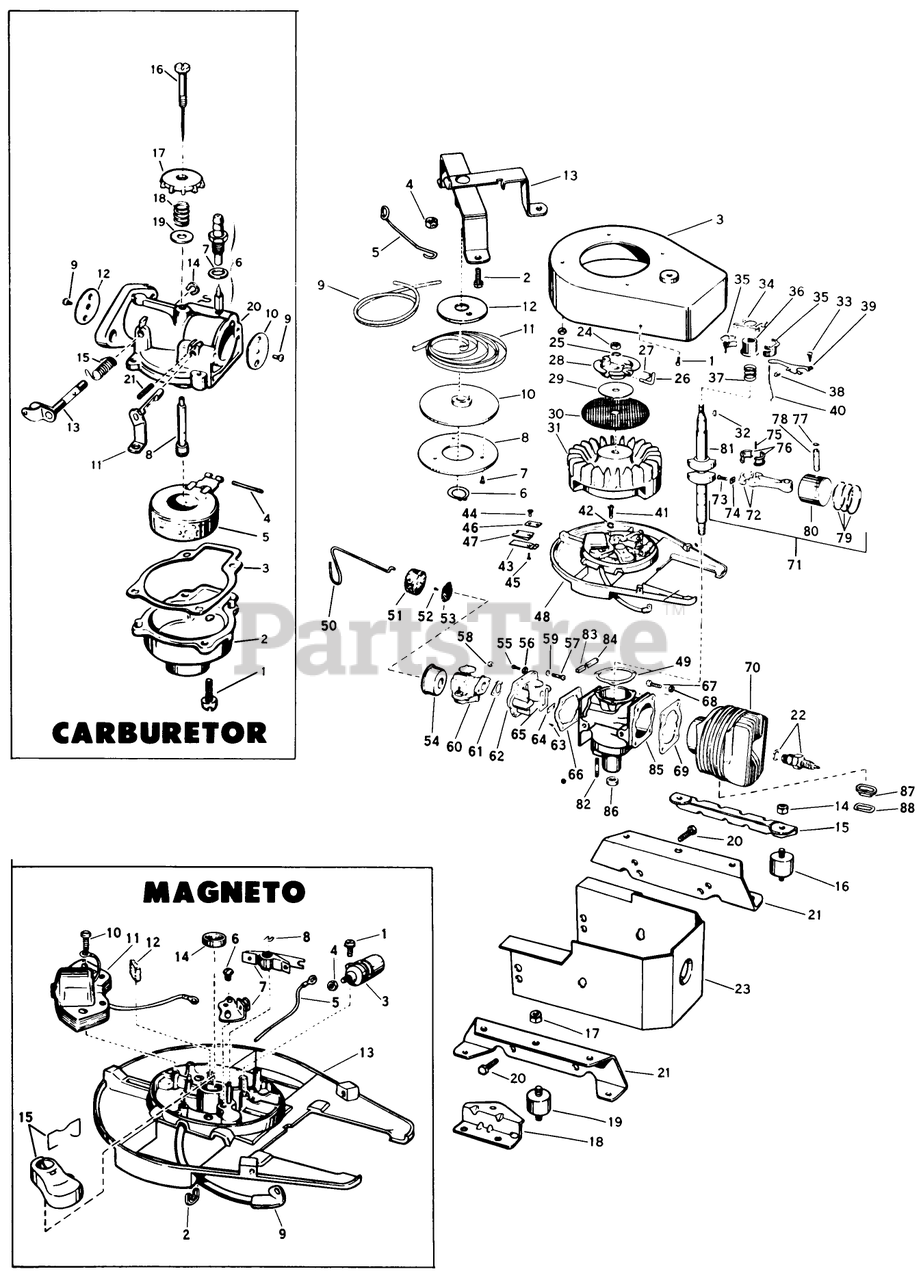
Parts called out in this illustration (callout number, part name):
1	SCREW S
1	Screw-Float Bowl to Carb.
6	Ring-Grip (Starter Brg. Pin)
7	BREAKER AY. S
8	Plate-Pulley
9	Rope-Starter
9	Screw-Choke Disc
11	RECOIL SPRING
12	Washer-Starter Spring Ret.
13	Armature Plate, Bearing, and Oil Seal Assembly
15	Bracket-Shock Mounting, Housing, Left
15	SPRING
16	Mount-Rubber, Left
16	NEEDLE AY. S
18	Bracket-Shock Mounting, Housing, Right
18	Spring-Ndl. Adj.
19	Mount-Rubber, Right
20	Screw-Stabilizer Bracket
21	Bracket-Shock Mtg., Engine
21	Spring-Choke Lever
22	Spark Plug
23	Shield-Cylinder and Crankcase
26	PIN - STARTER
36	COLLAR S
37	Spring-Governor
38	WEAR BLOCK S
39	GOVERNER LEVER AY
40	WEAR BLOCK S
45	Screw Shut-off Switch
47	Cover-Shut-off Switch Contact
49	GASKET S
50	Clip-Air Filter
51	ELEMENT
54	Cup-Air Filter
55	SCREW S
58	STOP NUT
61	GASKET S
64	PLATE-BACKUP, REED
76	LINER ASM
81	Crankshaft
82	Stud-Crankcase to Muffler
83	Shield-Dust, Crankcase, Right
84	Shield-Dust, Crankcase, Left
